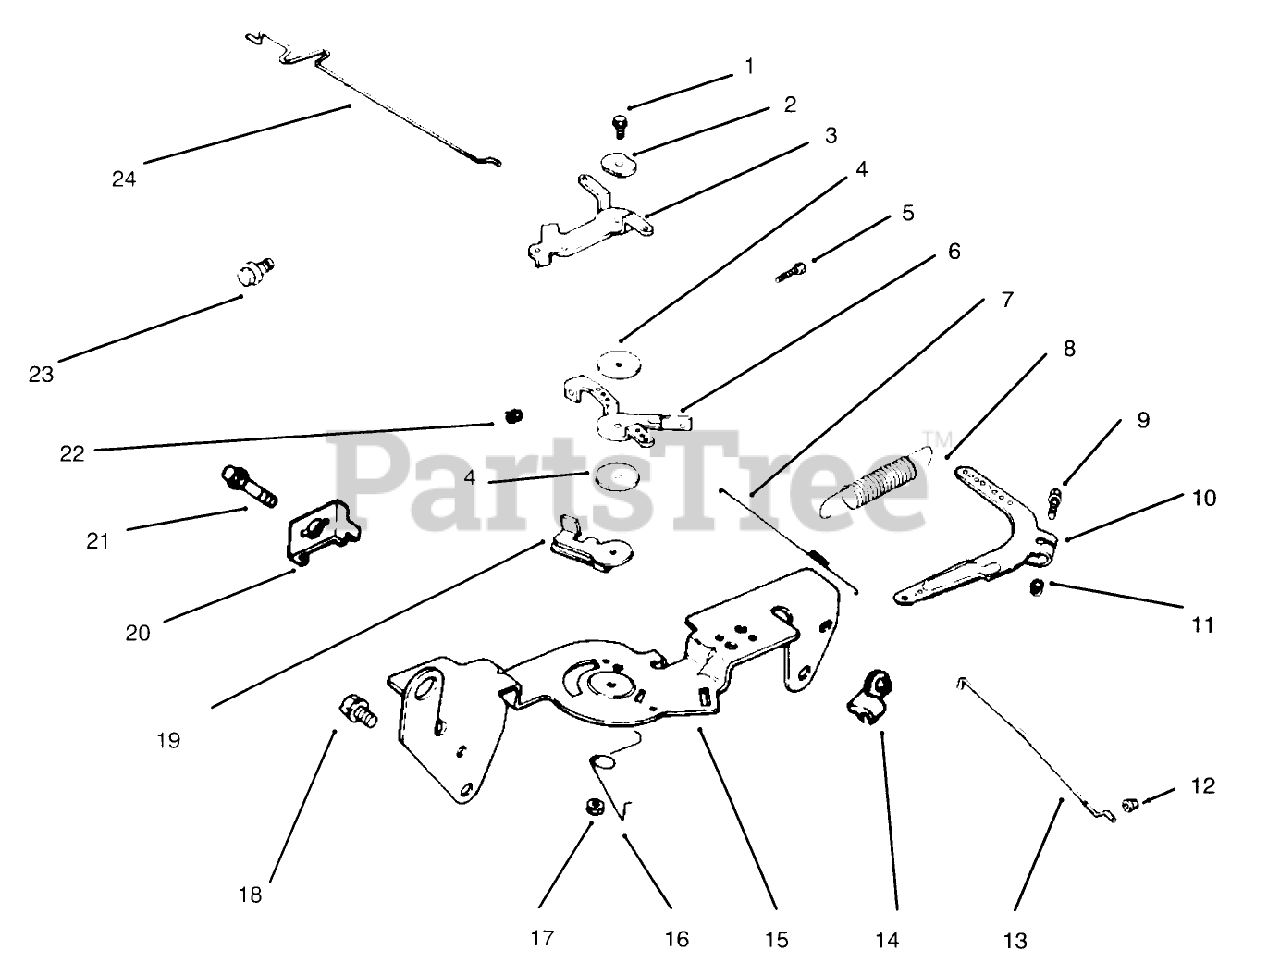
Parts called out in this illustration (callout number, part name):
1	Screw
2	Washer-Wave
3	Lever-Choke
4	Washer
6	Lever-Throttle Control
7	Spring-Linkage
8	Spring-Governor
9	Screw
10	Lever-Govenor
12	Bushing-Linkage
13	Linkage-Throttle
14	Bushing-Linkage
15	Bracket-Control
16	Spring-Choke Return
17	Nut
18	Screw
19	Lever-Actuator, Throttle
20	Clamp
21	Screw
22	Nut
23	Screw
24	Linkage-Choke
